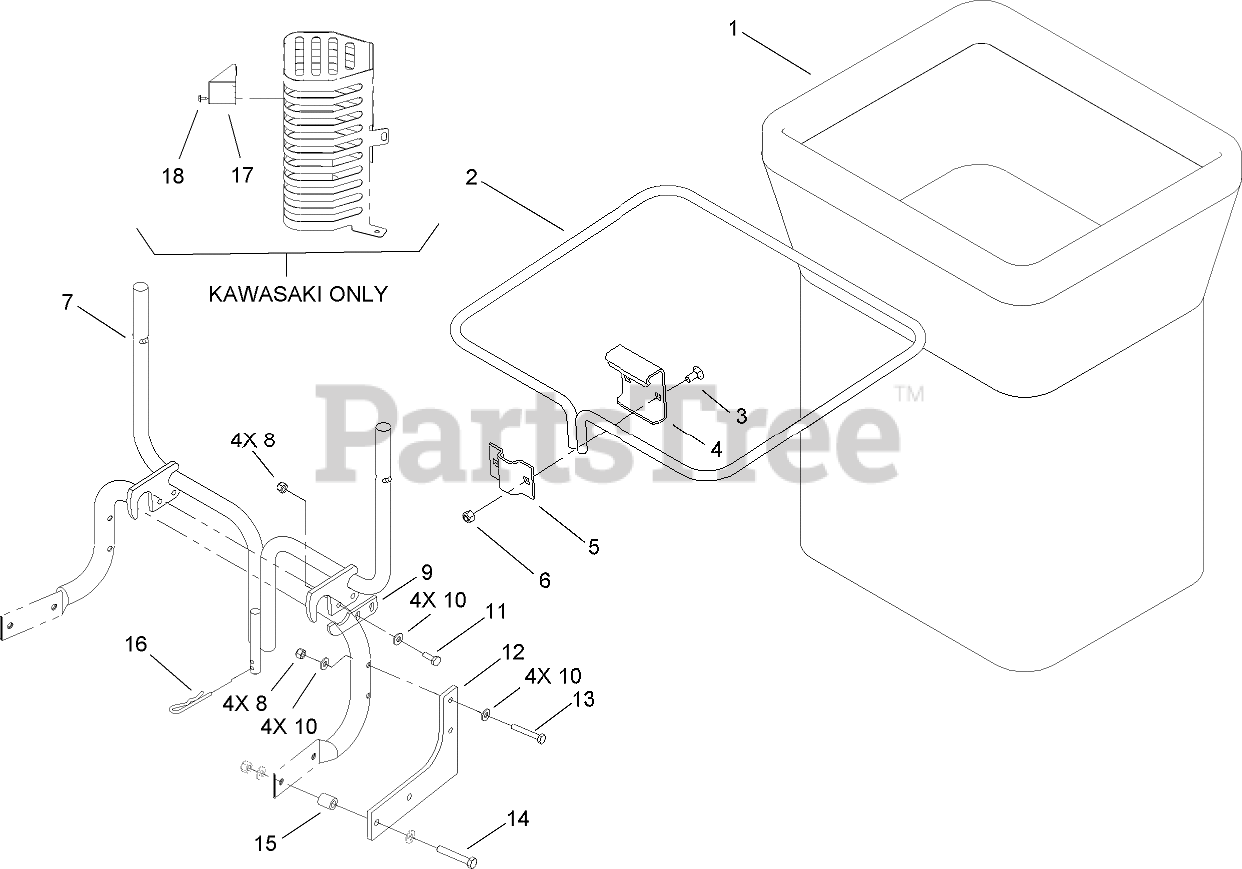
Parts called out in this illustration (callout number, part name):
1	BAG-DEPTH
2	FRAME-BAG
3	BOLT-CARR
4	HANGER-BAG
6	NUT-LOCK, NI
7	BAGGER BRACKET ASM
8	NUT-LOCK, NI
9	PLATE-BAGGER
10	WASHER-FLAT
11	SCREW-HH
12	GUSSET-BAGGER
13	SCREW-HH
14	SCREW-HH
15	SPACER
16	PIN-COTTER, HAIR
17	DEFLECTOR
18	SCREW-HWHTF
